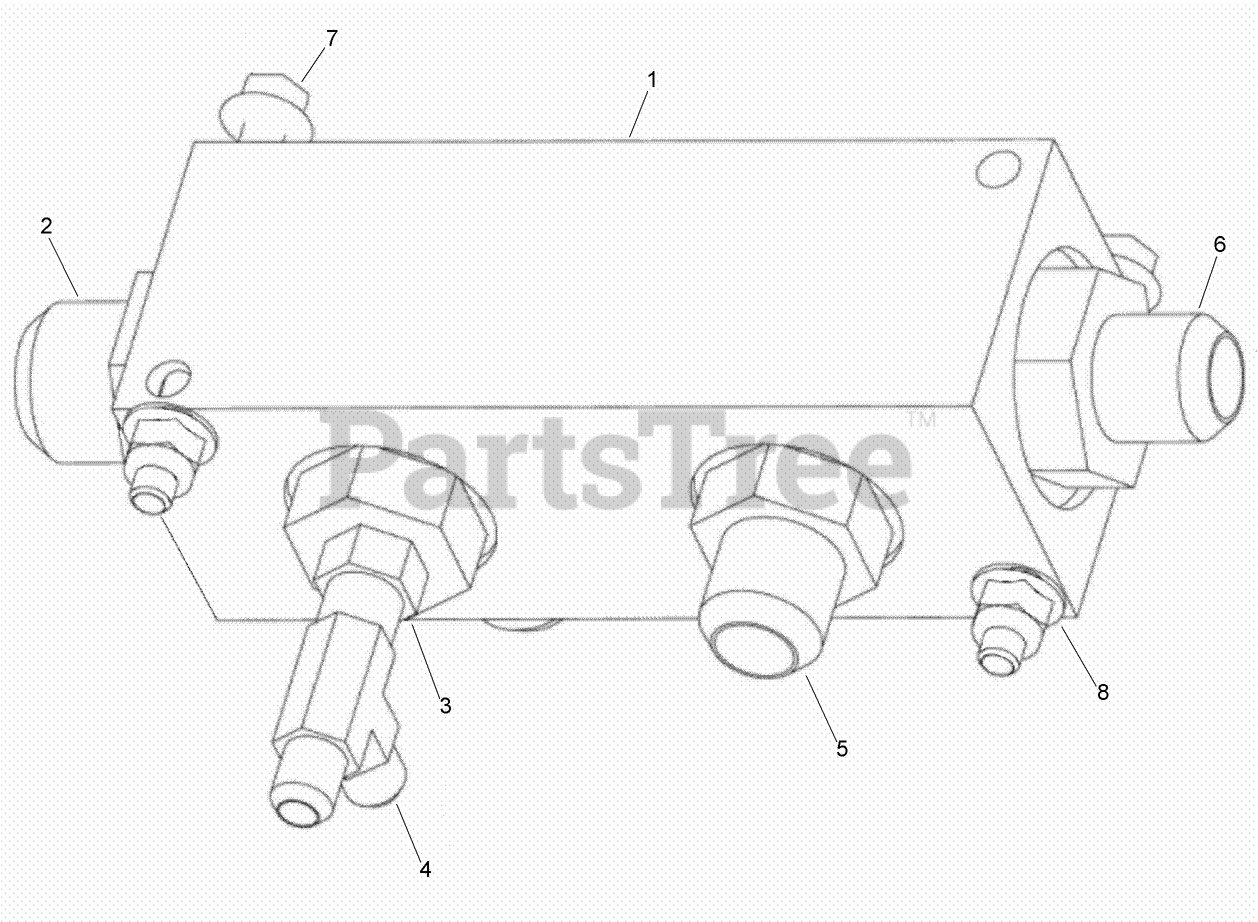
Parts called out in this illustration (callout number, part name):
1	MANIFOLD ASM (HYD RETURN)
2	FITTING-STRAIGHT
3	ADAPTER-STRAIGHT
4	TEE-Swivel Run 37FL, 3/8 x 3/8 x 3/8
5	FITTING-STRAIGHT
6	CONNECTOR-Str Thd 3/4, 37FL-ORB 1.0
7	SCREW-FLANGE
8	NUT-TORQUE, PREVAILING
